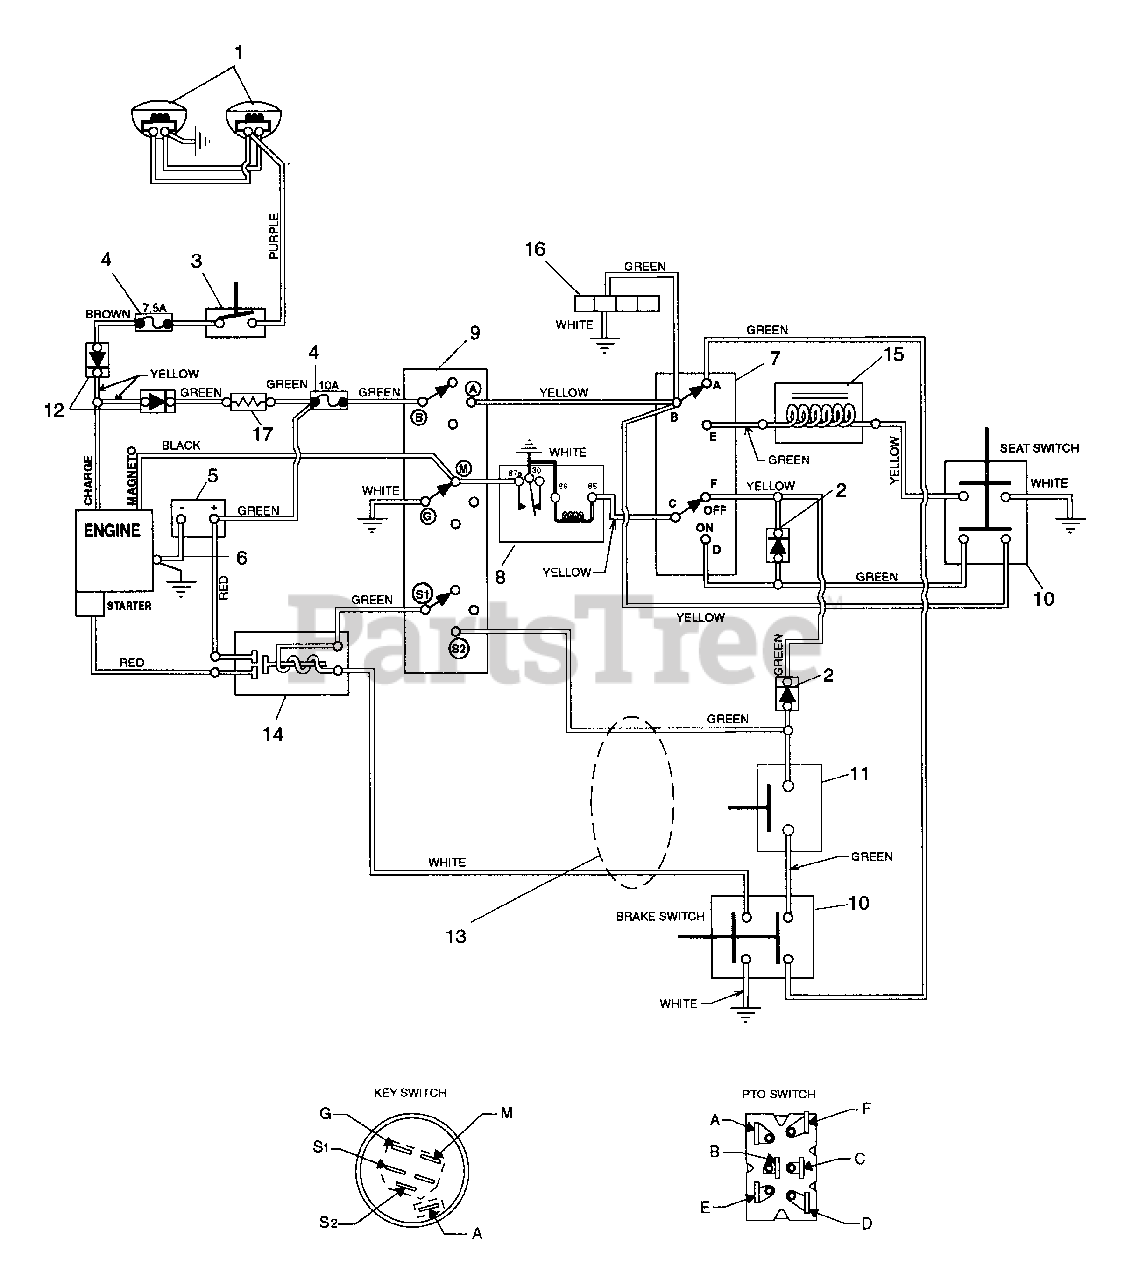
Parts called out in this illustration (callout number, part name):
1	HEADLIGHT- L.H.
1	HEADLIGHT- R.H.
2	MOLDED DIODE PLUG 1 AMP
3	LIGHT SWITCH
4	7.5 FUSE
4	10 AMP FUSE
5	BATTERY
6	GROUND CABLE .31X22.00X.31
7	SWITCH ASSEMBLY- PTO
8	RELAY
9	KEY SWITCH
10	SWITCH- DOUBLE POLE N.O./N.O.
11	SWITCH-NEUTRAL START N.O.
12	DIODE & HOUSING
13	WIRE HARNESS- YT12G
14	SOLENOID
15	ELECTRIC CLUTCH/BRAKE(1.8AMP)
16	HOUR METER W/ LEADS
17	RESISTOR- 1 OHM 25 WATT
17	REGULATOR KIT
